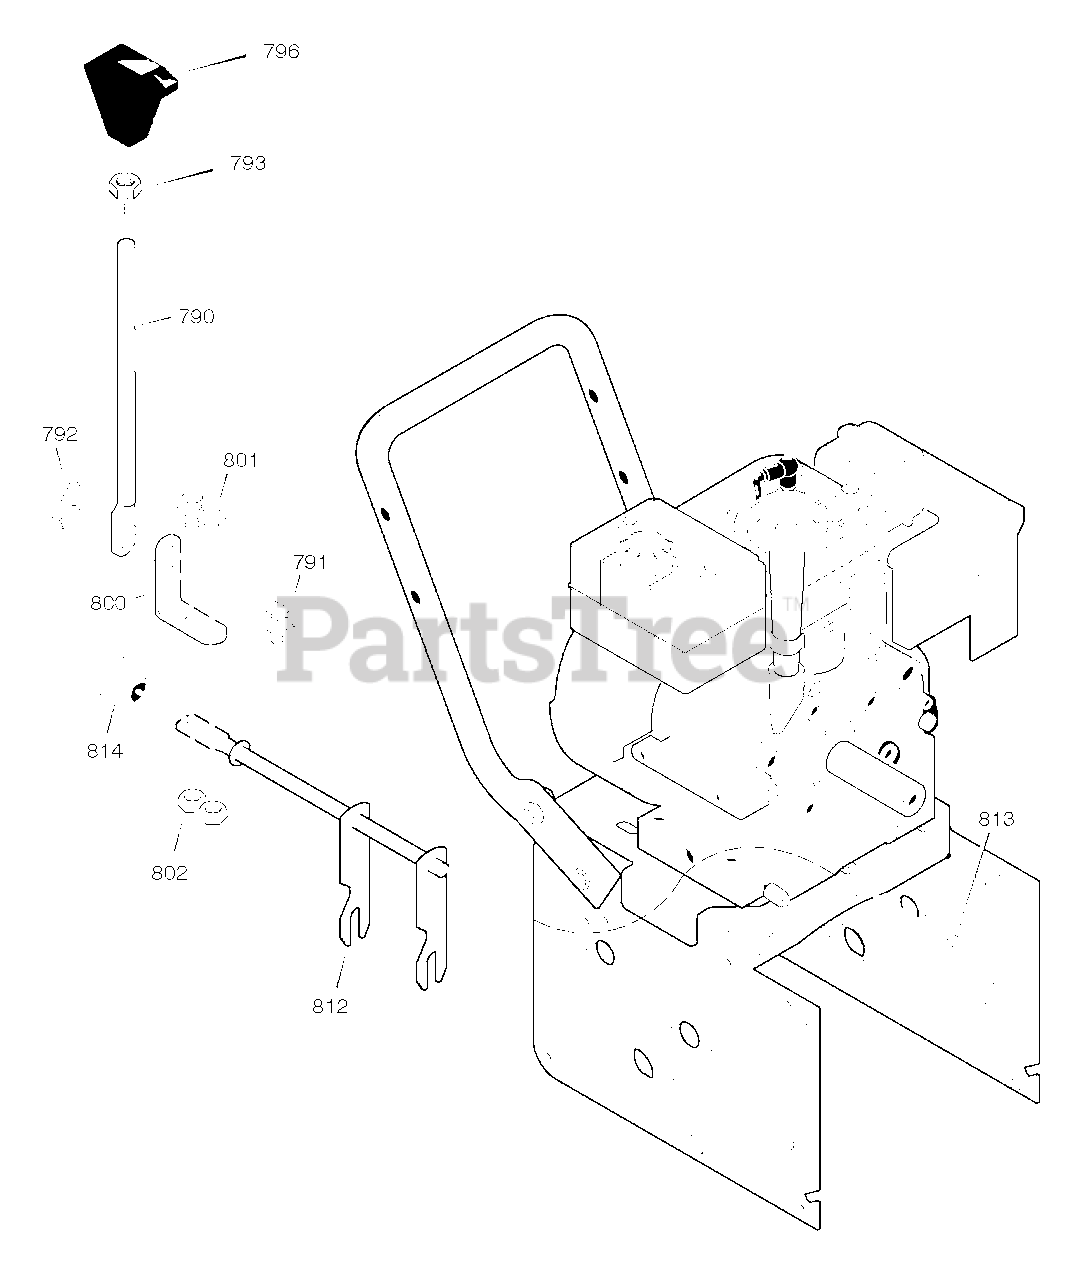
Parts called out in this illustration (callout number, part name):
790	ROD, SHIFT
791	SCREW, 1/4-20X.75
792	NUT, 1/4-20
793	NUT, JAM
796	KNOB
800	LEVER, SPRING
801	SCREW, 1/4-20X.75
802	NUT, 1/4-20
811	BEARING, FLANGED
812	ROD ASSY., SPEED SELECT
813	RETAINER, RING
